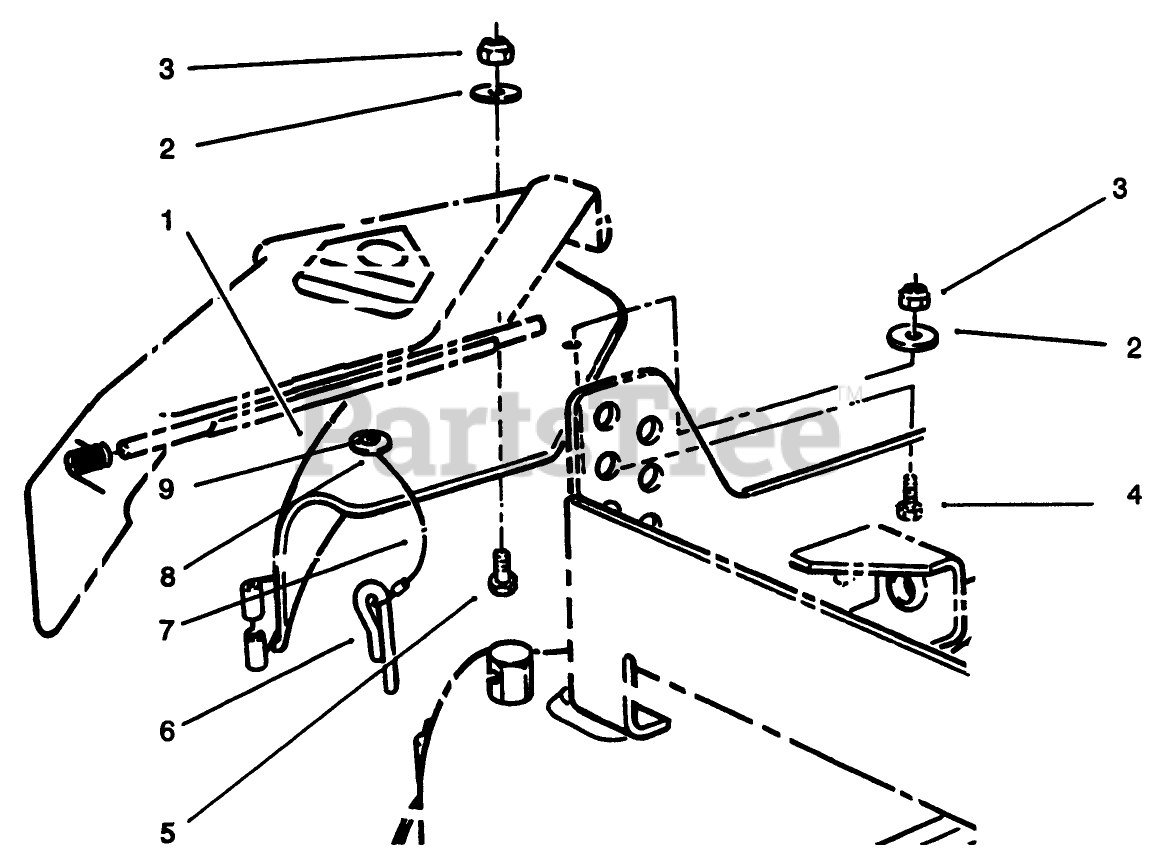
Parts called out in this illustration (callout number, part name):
1	Mulcher Cover Assembly (Incl. Ref. #6-9)
2	WASHER-PLAIN
3	NUT-LOCK, NI
4	SCREW-HH
5	SCREW-HH
6	PIN-LOCKING, CHUTE
7	LANYARD
8	Washer
9	RIVET-BLIND
